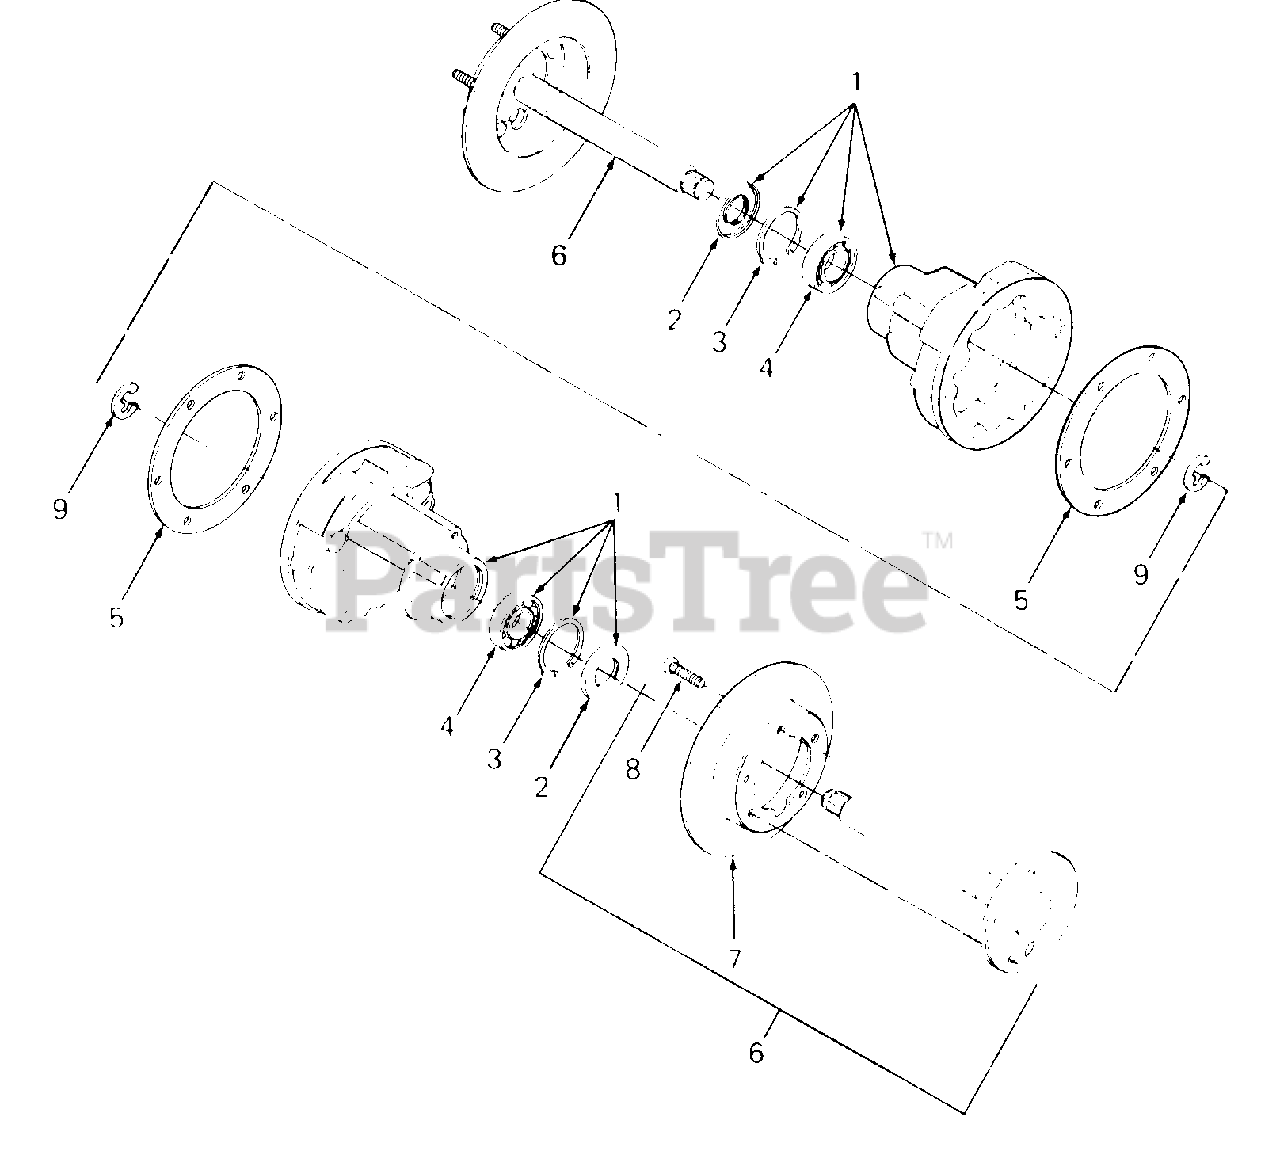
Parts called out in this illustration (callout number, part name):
1	Carrier Assy, Rear Axle
2	Seal, Oil
3	Ring, Retaining
4	Bearing, Ball
5	Gasket, Carrier
6	Axle Assy, Rear
7	Disc, Brake
8	Bolt, Lug
9	Retainer, E-Ring
